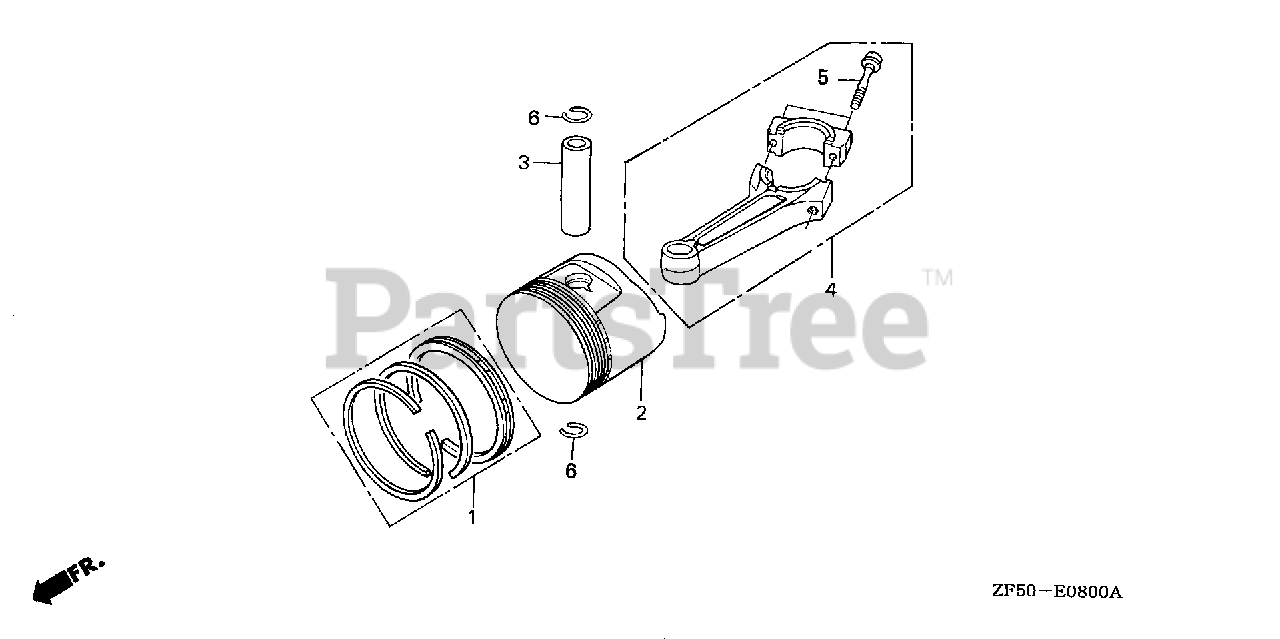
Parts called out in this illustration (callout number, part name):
1	RING SET, PISTON (STD) (NIPPON)
1	RING SET, PISTON (0.25)
1	RING SET, PISTON (0.50)
2	PISTON (STD)
2	PISTON (0.25)
2	PISTON (0.50)
3	PIN, PISTON
4	ROD ASSY., CONNECTING
5	BOLT, CONNECTING ROD
6	CLIP, PISTON PIN (20MM)
